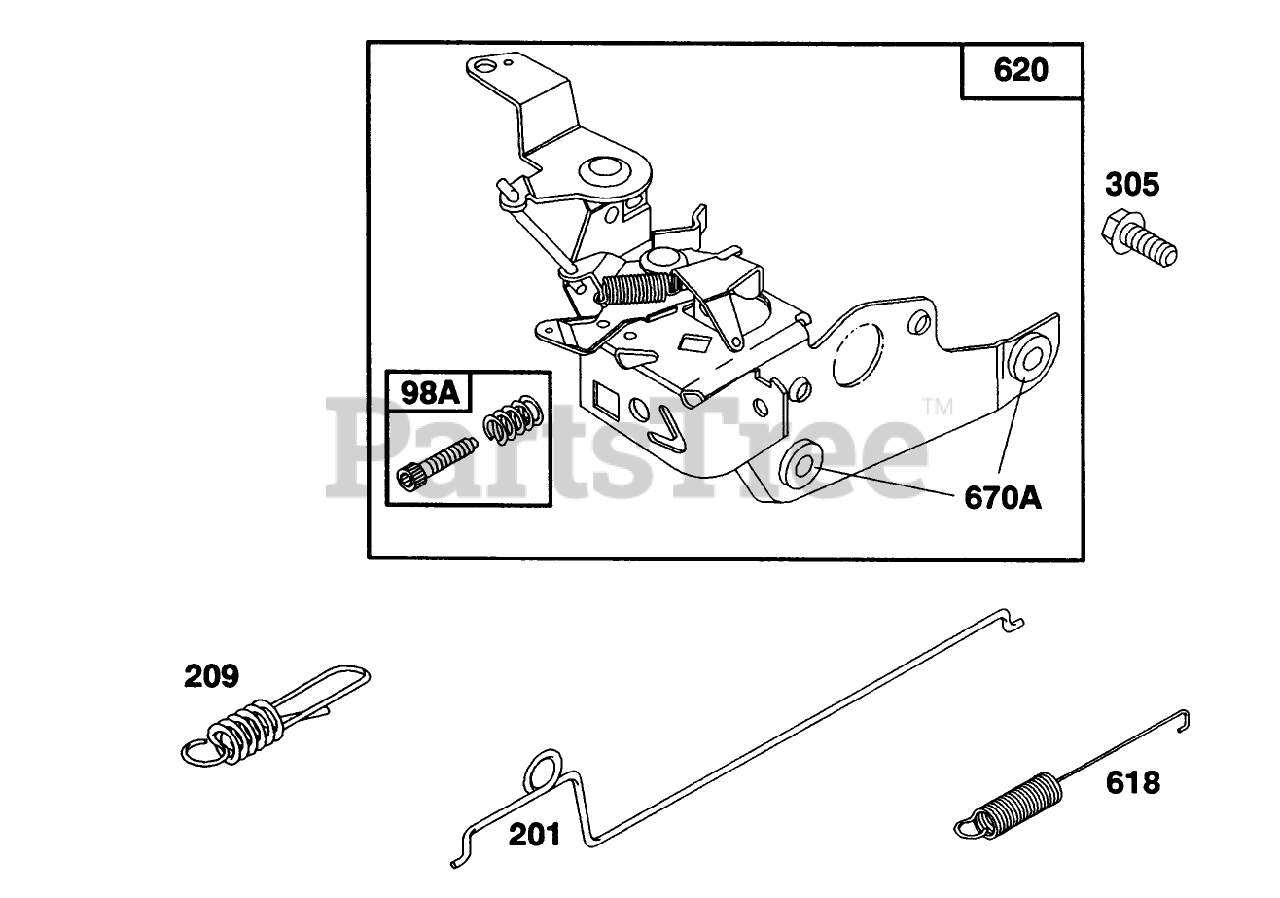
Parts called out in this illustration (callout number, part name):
98A	Screw Assy.
201	Link-Govemor
209	Spring-Govemor
305	Screw-Sem
618	Spring-Choke
620	Bracket Assembly
670A	Spacer
